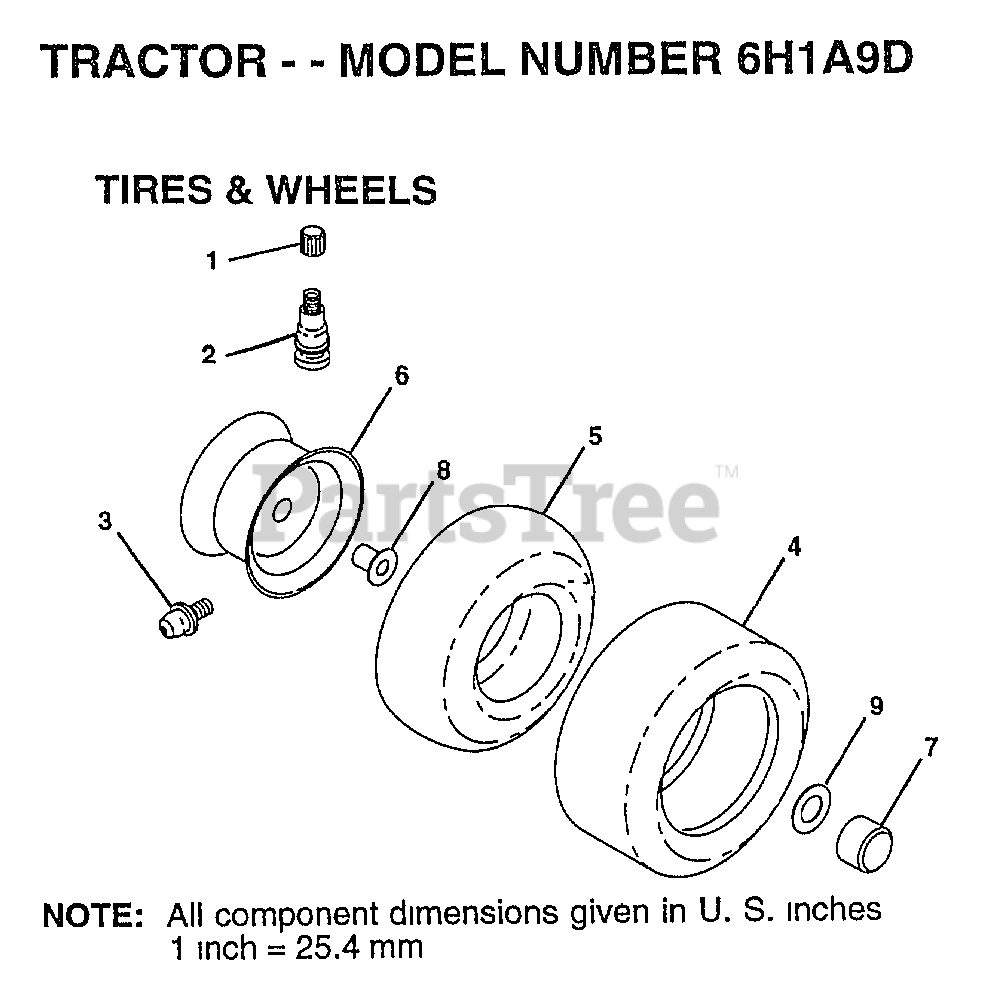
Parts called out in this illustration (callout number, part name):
1	VALVE CAP
2	VALVE STEM LT
3	FITTING LT
4	TIRE
5	TUBE.5.3/4.5/6
6	"RIM FRONT 6"""
7	HUB CAP
8	"FLANGE, BEARING"
9	WASHER
